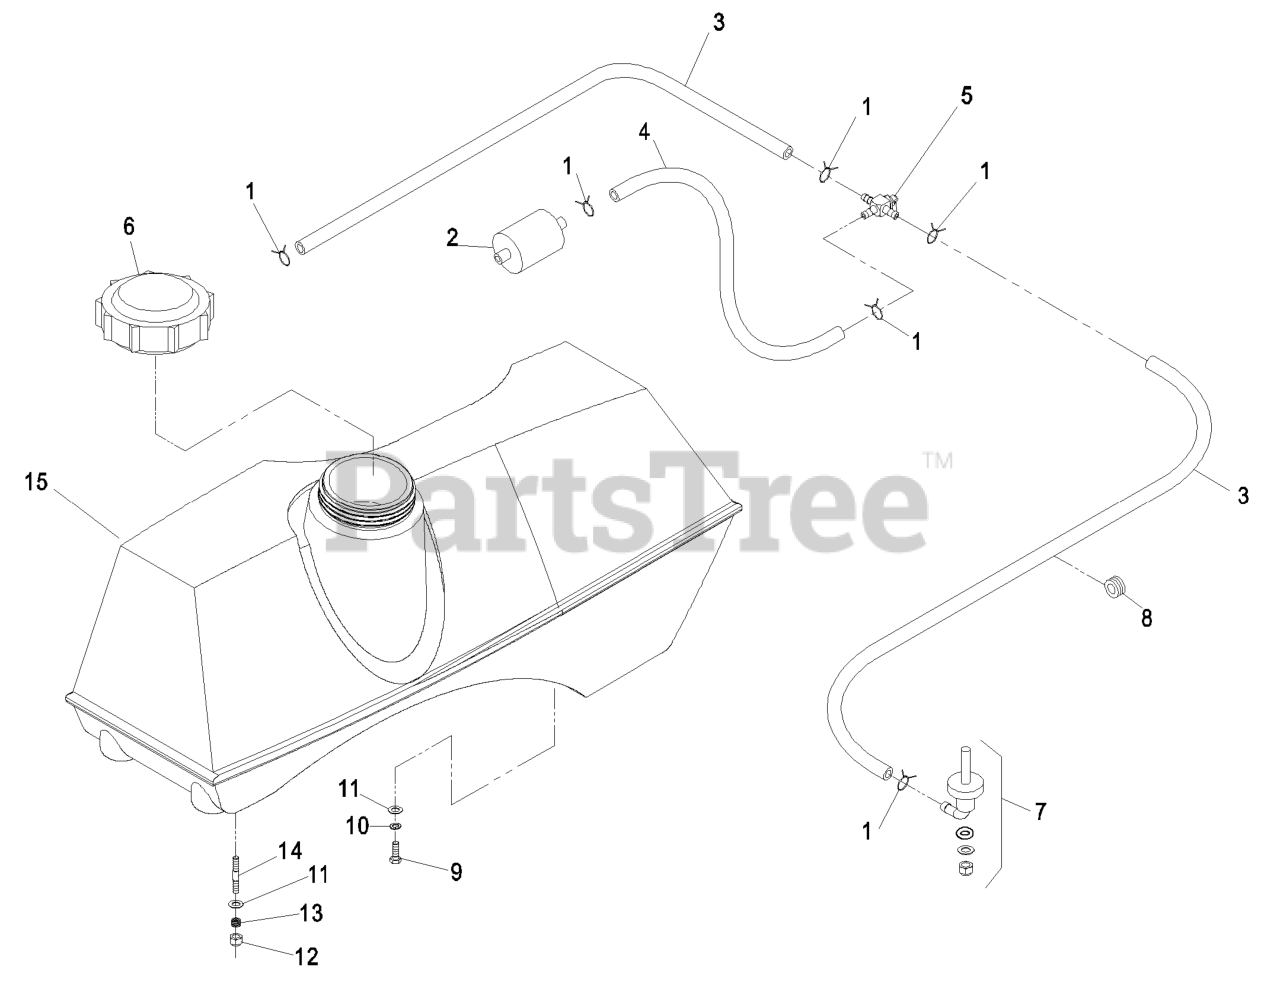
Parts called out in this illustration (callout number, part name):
2	Kohler Part No. 2405002 Fuel Filter
4	HOSE-FUEL
5	VALVE-FUEL
7	FITTING-FUEL, BULKHEAD
8	GROMMET
9	SCREW-HH
10	WASHER-LOCK
11	WASHER-PLAIN
12	NUT-LOCK, NI
13	SPRING-TANK, FUEL
14	STUD
